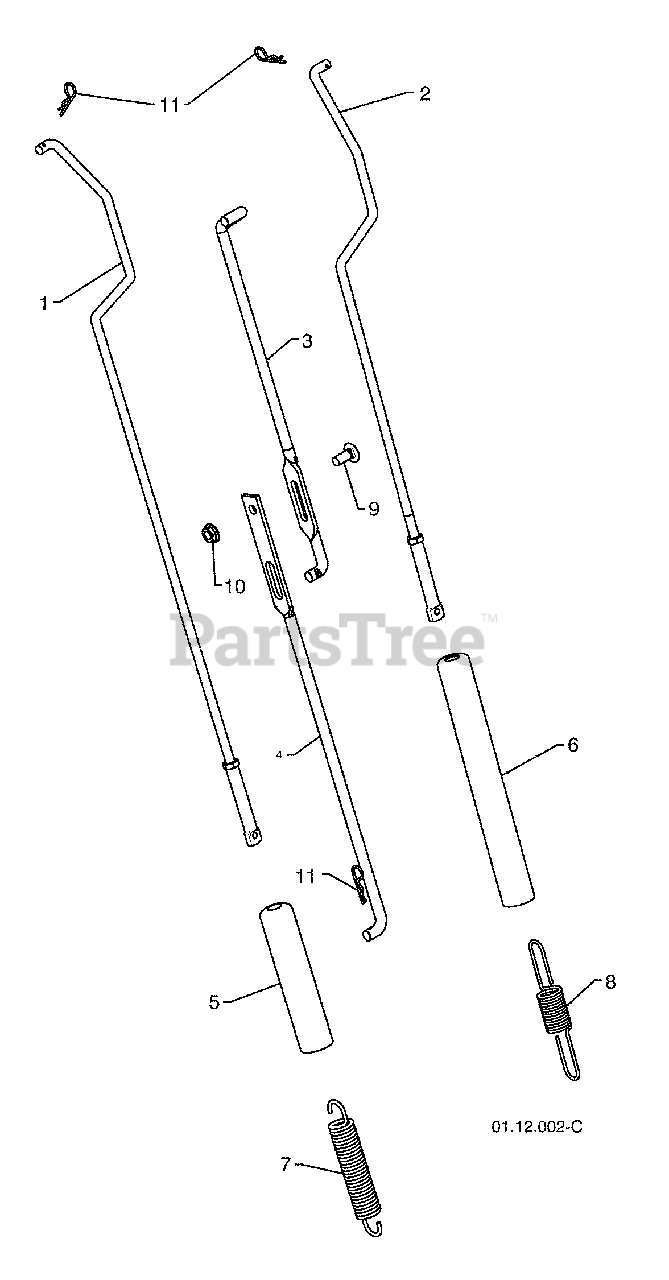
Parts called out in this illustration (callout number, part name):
1	IMPELLER ROD ASSEMBLY
2	TRACTION ROD ASSEMBLY
3	SHIFTER ROD TOP
4	SHIFTER ROD BOTTOM
5	SPRING SLEEVE
6	SPRING SLEEVE
7	IMPELLER SPRING
8	TRACTION SPRING
9	CARRIAGE BOLT 5/16-18 X .750
10	NUT 5/16-18
